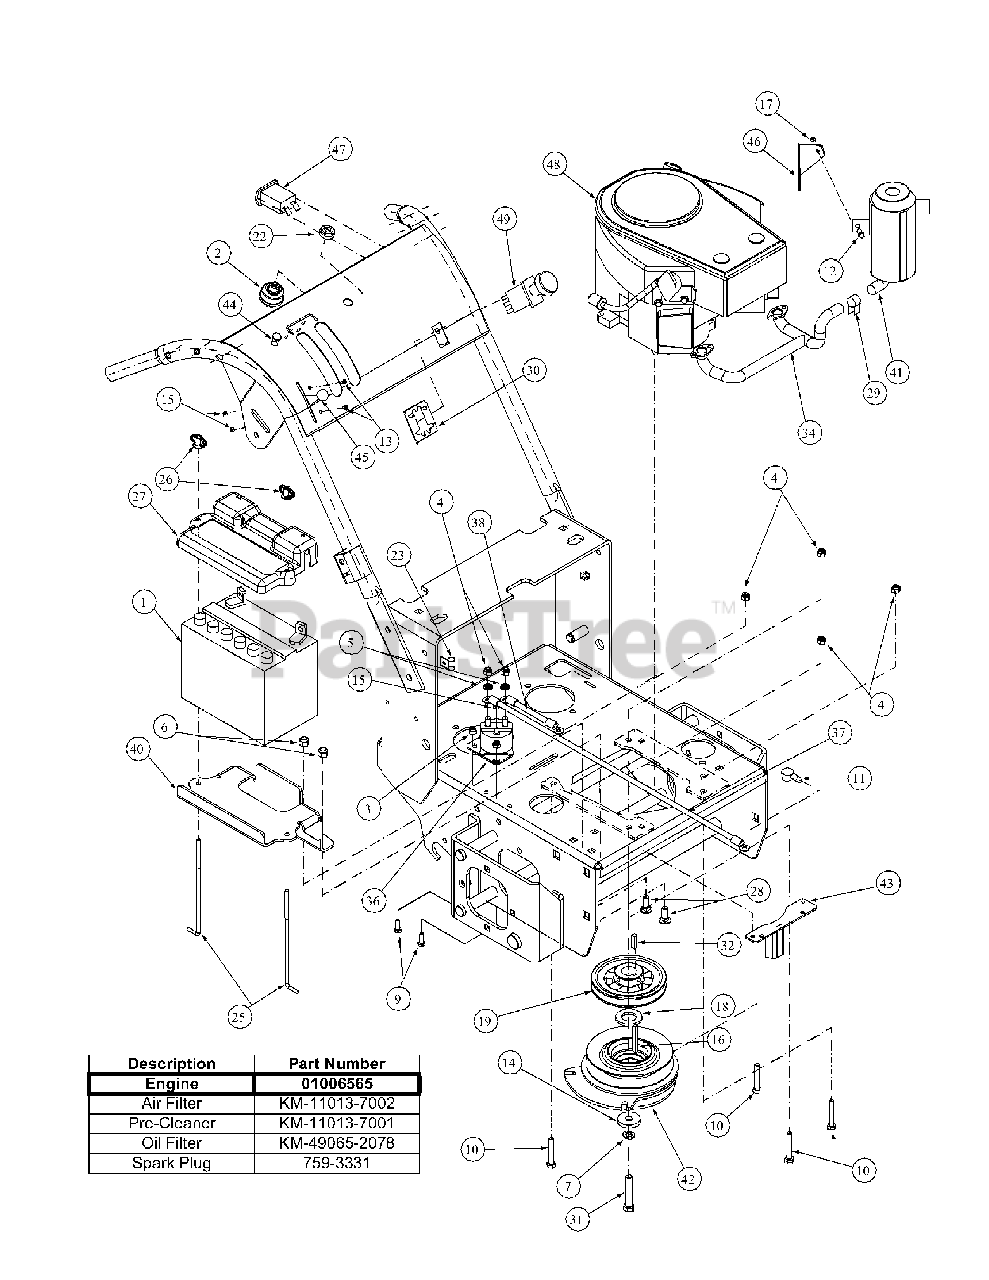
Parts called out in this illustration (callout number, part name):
1	Battery 12V
2	Ignition Switch
3	Lock Nut Nylon Insert, 1/4-20
4	Nylock Nut, 5/16-18
5	Lock Washer, 5/16
6	Nylock Nut, 3/8-16
7	Lock Washer, 7/16
9	Hex Cap Screw, 1/4-20, .75
10	Hex Cap Screw, 5/16-18 x 2
11	Rubber Boot, 1" OD
12	Hex Cap Screw, 5/16-18 x 3/4
13	Screw, Hex Washer w/slot, 10-32x1/2
14	Clutch Washer
15	Lock Nut, Nylon Insert, #10-32
16	Key Stick, 1/4 x 1/4 x 2
17	Lock Nut, 5/16-18
18	Washer
19	Sheave, 1" Bore with 2 Set Screws
20	Hydro Pump Drive Belt
22	Nut w/cap 5/8-32
23	Support Clamp 3/8 OD
24	Cable Battery, 10-1/4"
25	Hold Down Rod
26	Wing Nut w/Belle Washer, 1/4-20
27	Battery Cover
28	Carriage Bolt, 3/8-16 x 1
29	Muffler Clamp Assembly
30	Retainer Clip
31	Hex Cap Screw, 7/16-20, 2.00
32	Keystick, 1/4 x 1/4 x 1
33	Harness Hourmeter
35	Harness Kohler
36	Magnetic Solenoid Switch
37	24" Red Battery Cable
38	5" Red Battery Cable
39	Harness Adapter Kawasaki
40	Battery Bracket
41	Muffler, Kawasaki KM-49070-7002
42	Electric Clutch
43	Retainer Clutch Bracket Assembly
44	Cable Choke
45	Control Throttle w/Detent
46	Muffler Bracket
47	Hour Meter
48	17 HP Kawasaki Engine
49	Blade Clutch Switch
